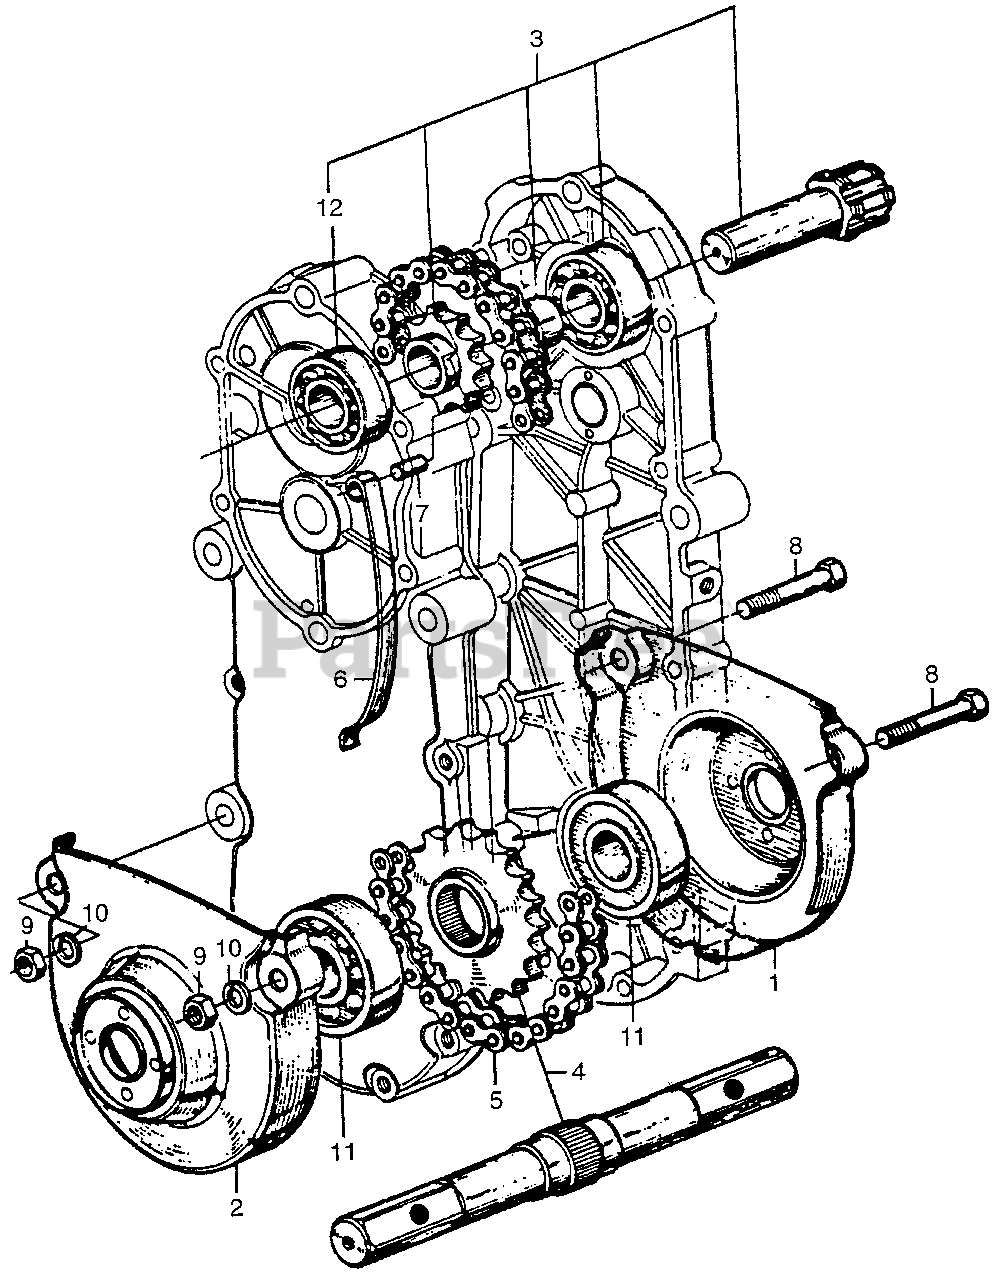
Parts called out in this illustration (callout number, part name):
1	PROTECTOR, R. CASE (NOT AVAILABLE)
2	PROTECTOR, L. CASE (NOT AVAILABLE)
3	SHAFT, FINAL (NOT AVAILABLE)
4	SHAFT, WHEEL (NOT AVAILABLE)
5	CHAIN, DRIVE (NOT AVAILABLE)
6	TENSIONER, CHAIN (NOT AVAILABLE)
7	SHAFT, TENSIONER (NOT AVAILABLE)
8	BOLT, HEX. (10X50)
9	NUT, HEX. (10MM)
10	WASHER, SPRING (8MM)
11	BEARING, RADIAL BALL (6205)
12	BEARING, RADIAL BALL (6202U)
